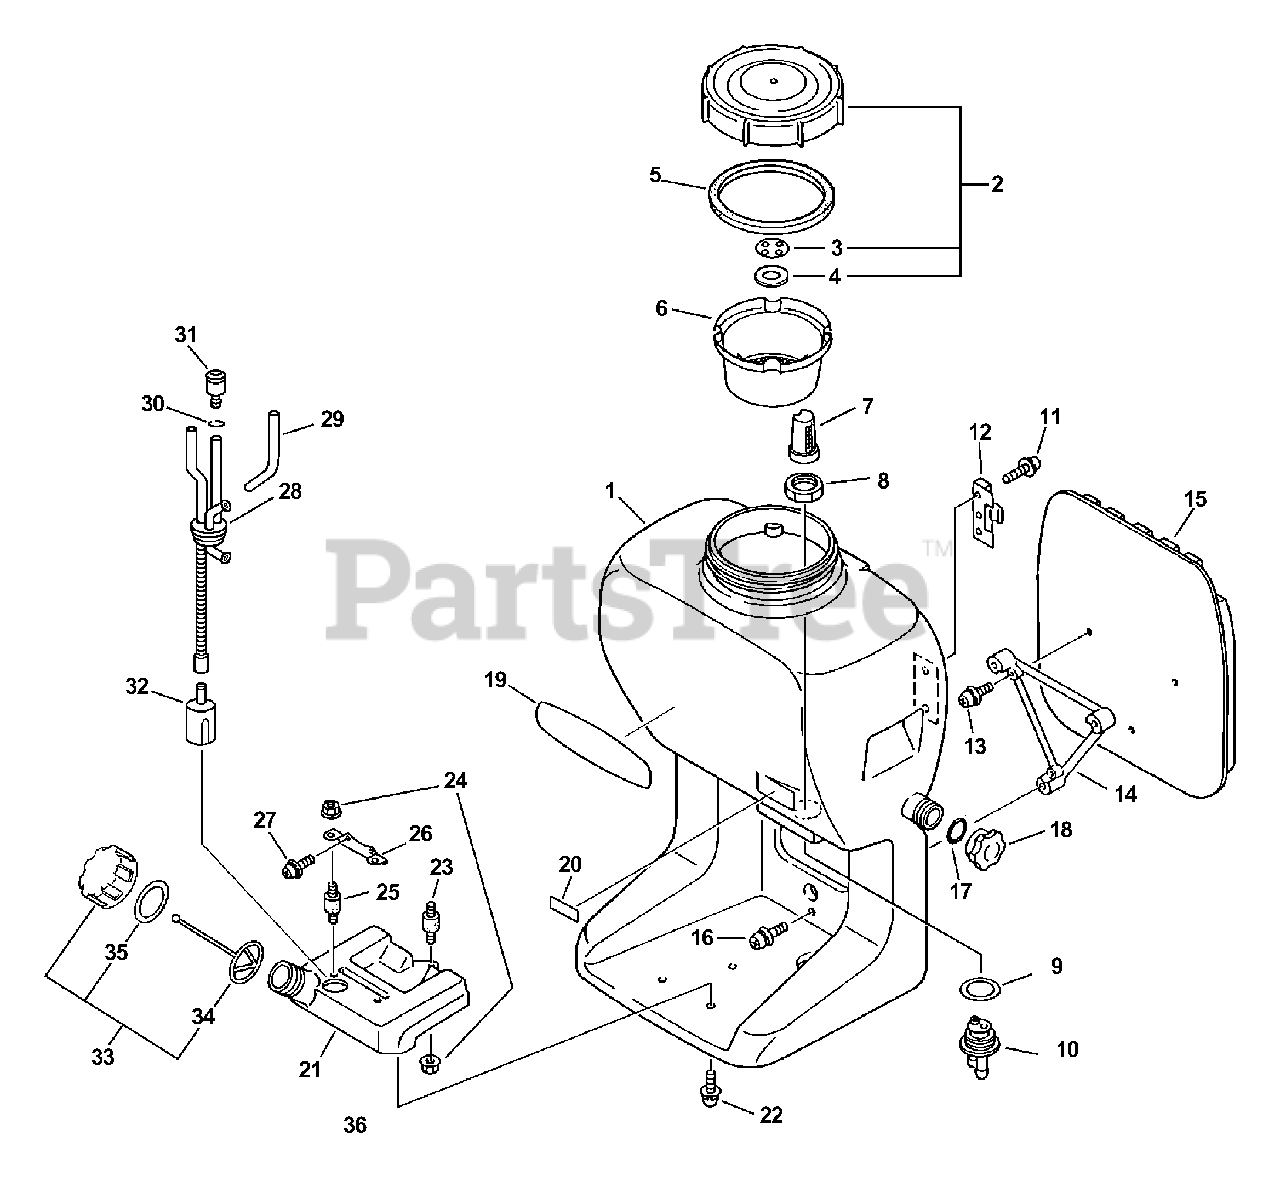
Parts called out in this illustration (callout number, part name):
1	TANK, CHEMICAL
2	CAP, CHEMICAL TANK
3	VALVE, AIR
5	GASKET, CAP
6	FILTER, CHEMICAL TANK
8	NUT, HOSE
11	SCREW - 6X20
12	HOLDER, NOZZLE
13	SCREW - 5X16
14	BRACKET, CUSHION
15	CUSHION, BACKPACK
16	SCREW - 5X16
17	O-RING - 28
18	CAP, DRAIN
19	LABEL - ECHO
20	LABEL - MODEL SHR-210
21	TANK, FUEL
22	SCREW - 6X14
24	NUT - 6 -- FLANGE
26	BASE, SWIVEL
27	SCREW - 5X10
28	FUEL PIPE KIT
29	PIPE - 3X6X100 -- CLEAR
30	CLIP - 5.5
31	VENT, FUEL TANK
32	FILTER, FUEL
33	CAP ASSY - ORANGE
34	CONNECTOR, CAP
35	GASKET, CAP
